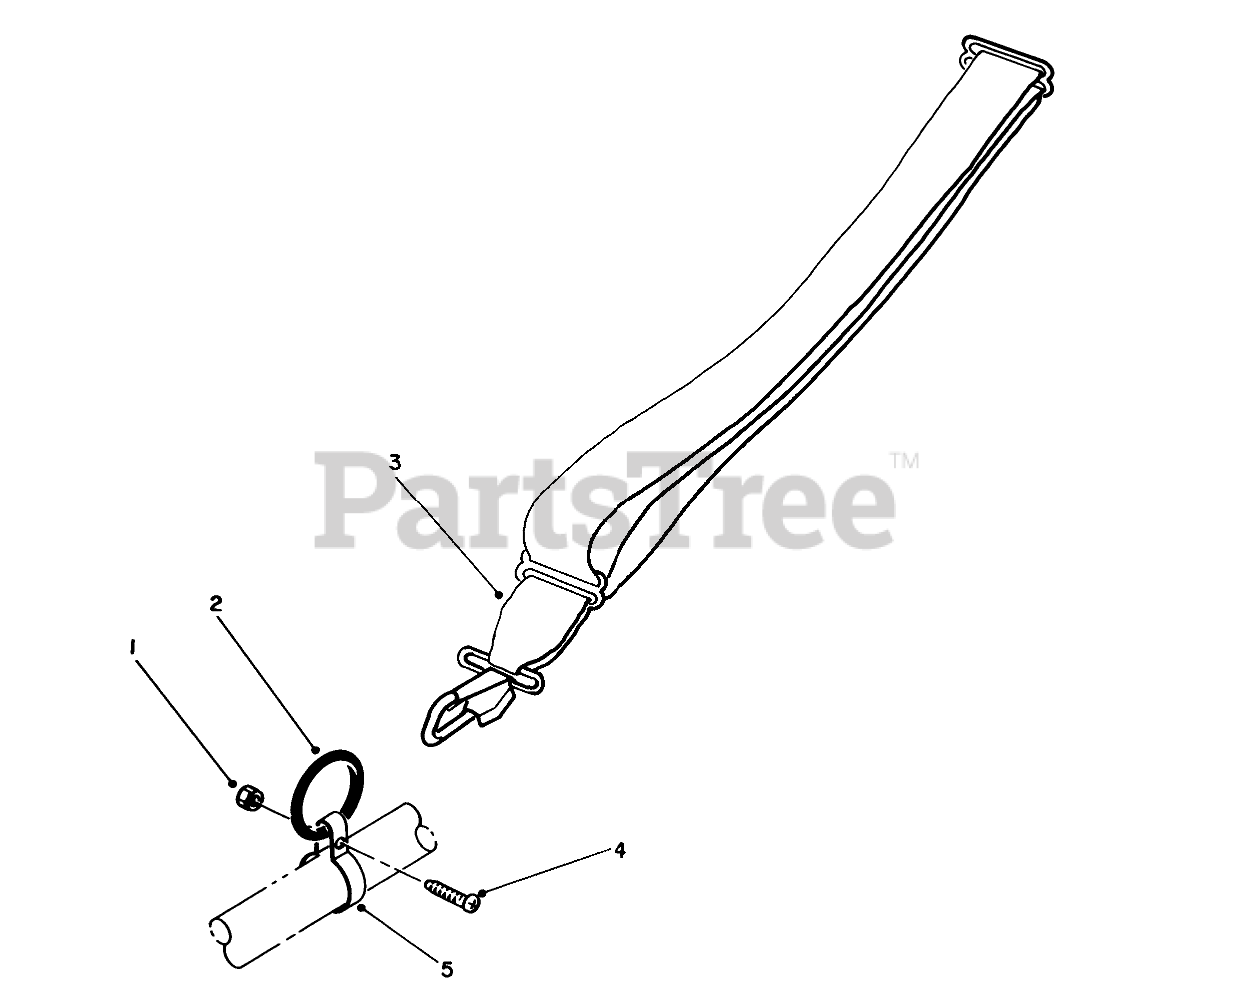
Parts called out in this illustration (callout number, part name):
1	NUT-LOCK, NI
2	Ring
3	Harness
4	SCREW-SRH
5	Clamp
